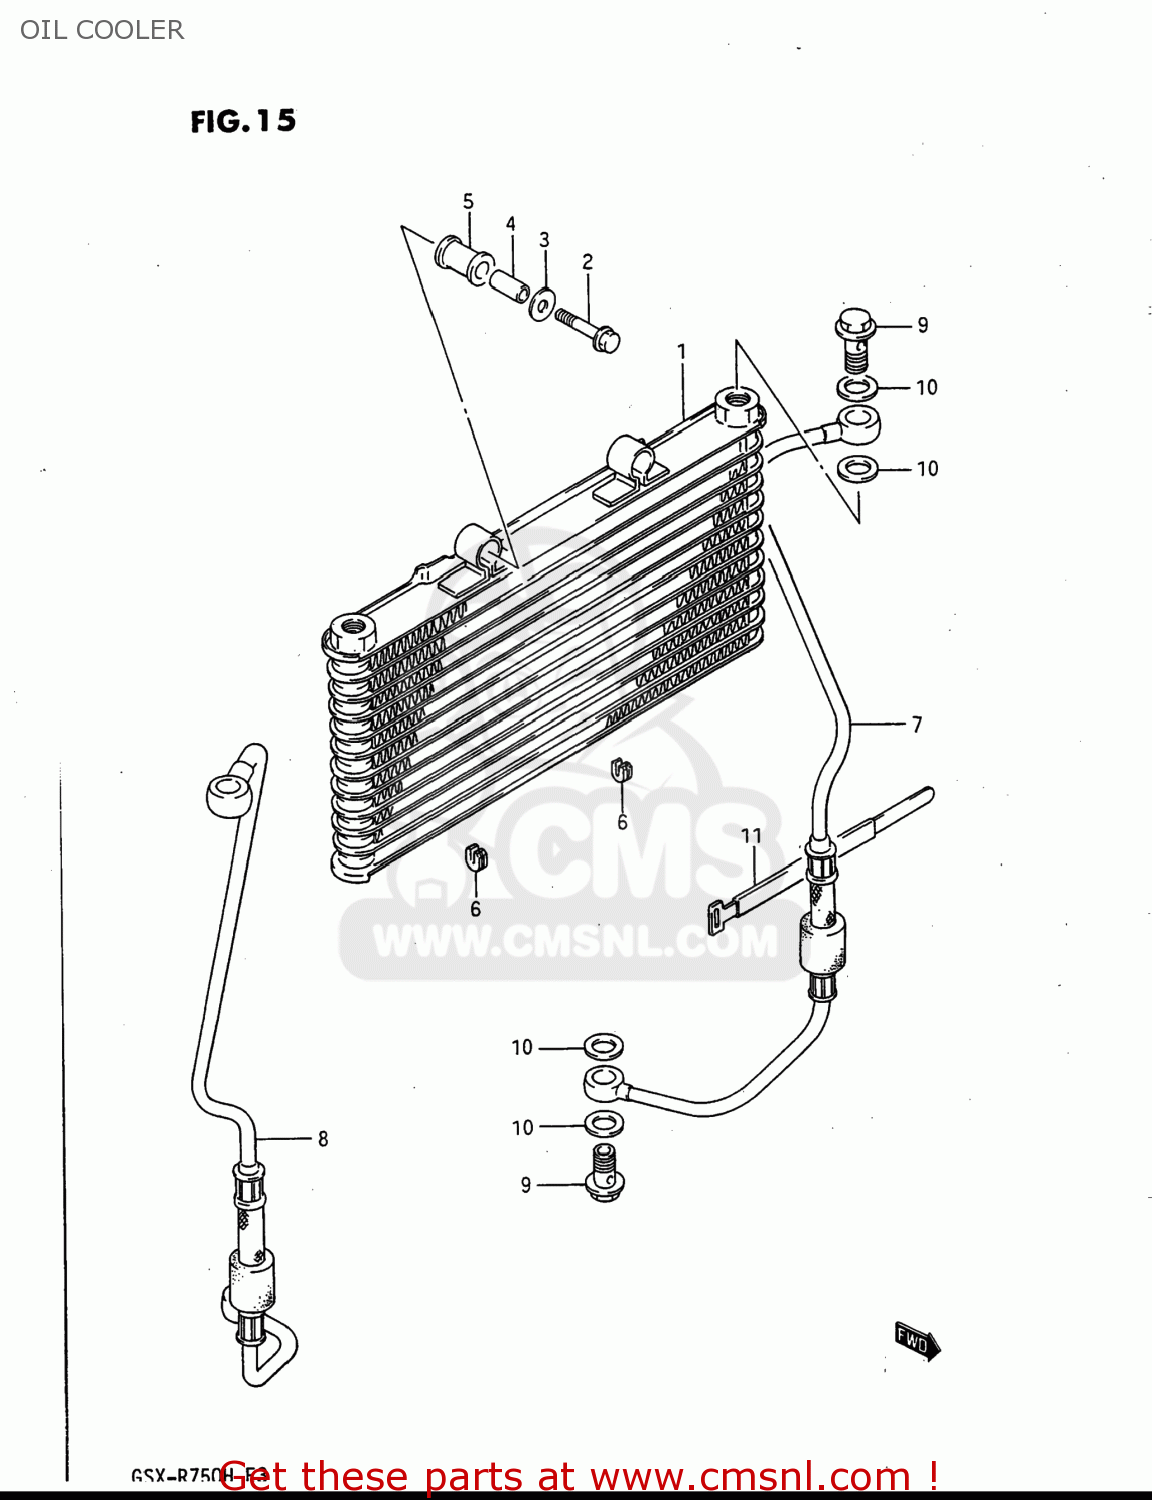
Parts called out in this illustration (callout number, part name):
1	COOLER ASSEMBLY,OIL
2	BOLT 8X40
3	WASHER(8.5X23X1.2)
4	SPACER (8.8X12X24.5)
5	CUSHION,OIL COOLER NO.1
6	CUSHION,OIL COOLER NO.2
7	HOSE,OIL
8	HOSE,OIL
9	BOLT,UNION
10	GASKET(16X22X2) (NAS)
11	CLAMP
